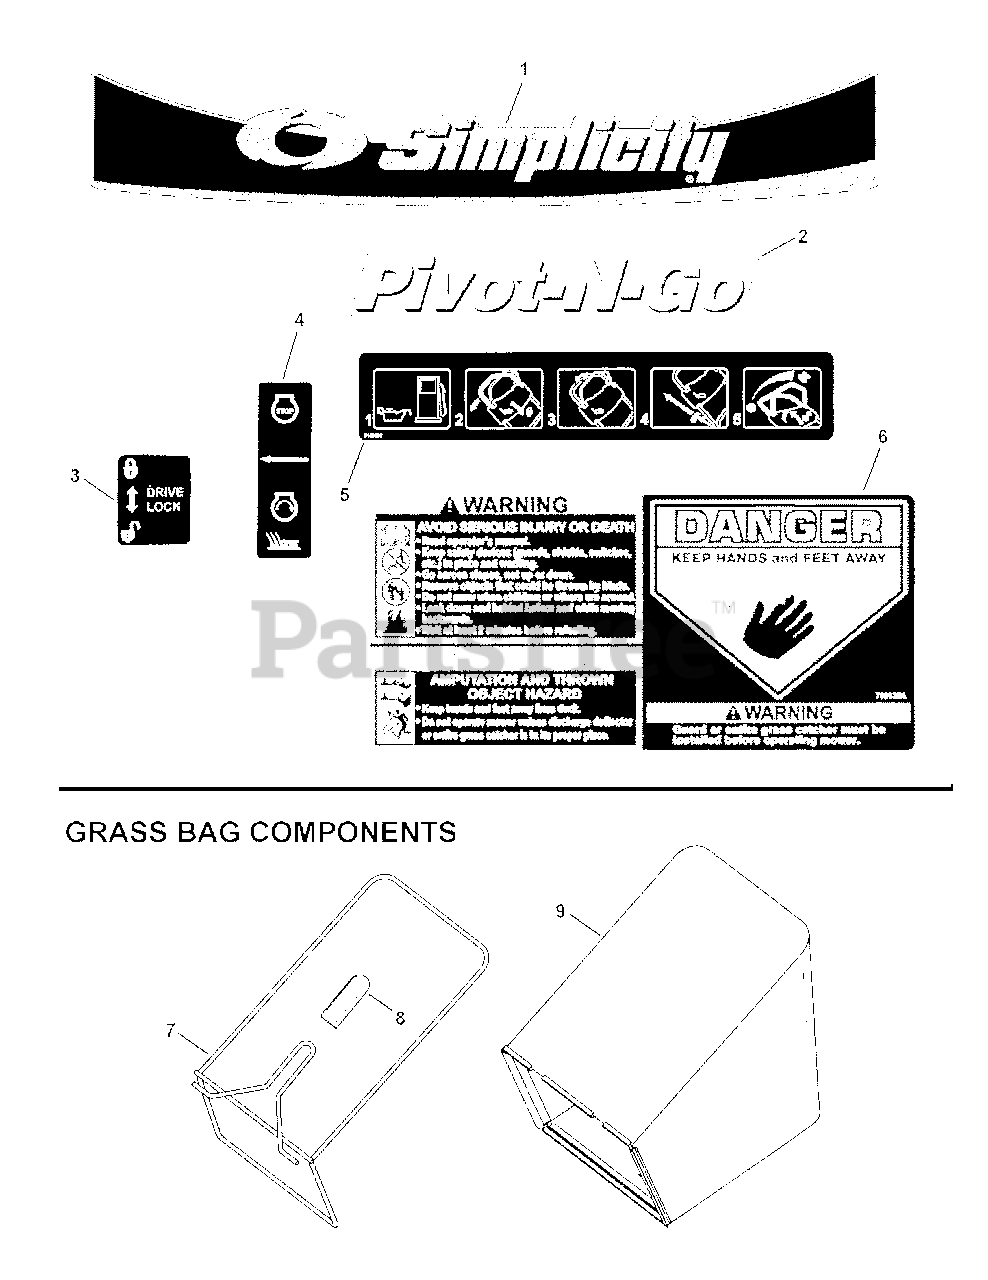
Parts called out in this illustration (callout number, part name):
1	DECAL, Simplicity Walk Mower, Cast Deck
2	DECAL, Pivot-N-Go, Simplicity
3	DECAL, Neutral Lock
4	DECAL, OPC Bail International Symbol
5	DECAL, Pivot, Handle
6	DECAL, Warning, Rear Discharge Door
7	WELDMENT, Catcher Frame (High) Black
8	GRIP, Rectangular (Black)
9	GRASS BAG, Rear Discharge, No Graphics
